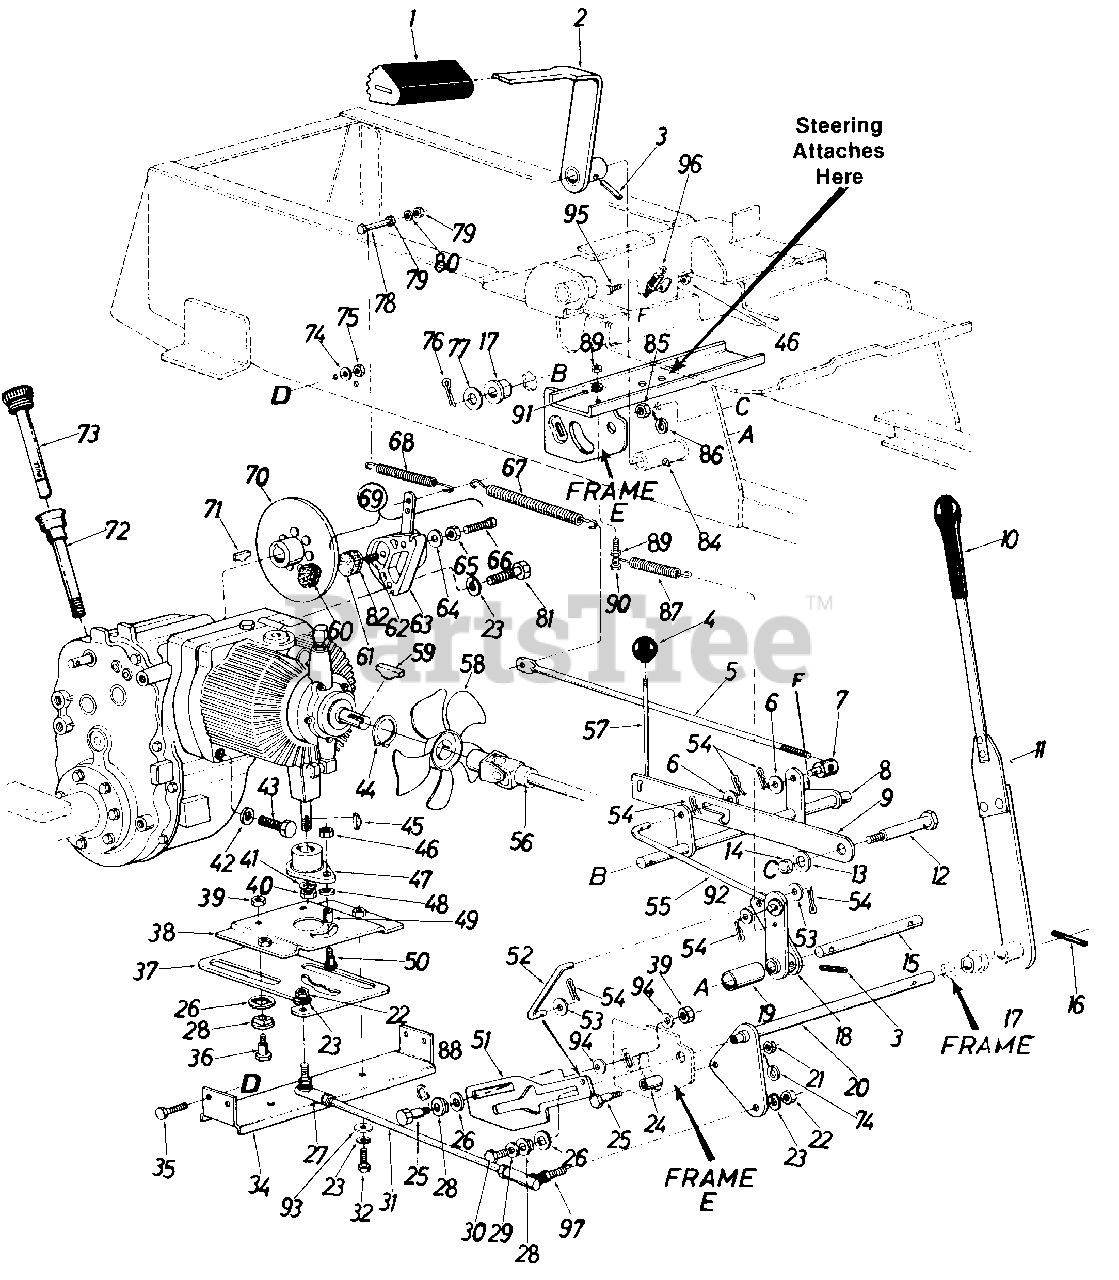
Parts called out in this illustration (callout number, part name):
1	Foot Pad
4	Ball Knob-Brake
5	Brake Rod
6	Fl-Wash. .375" I.D. x 1.00" O.D. x .030
7	Ferrule
8	Brake Transfer Shaft Ass'y.
9	Parking Brake Cam
10	G ri p
11	Control Arm Ass'y. Comp.
12	Shld. Scr. .62 Dia. x 2.75" Lg.
13	Fl-Wash. .460 I.D. x 1.24 O.D. x .06
14	Push Speed Nut for .625 Dia. Shaft
15	Brake Pivot Shaft
16	Spring Pin Spiral 1/4" Dia. x 1.50" Lg.*
17	Hex Flange Brg. Plastic .62 I.D.
18	Brake Hub Ass'y.
19	Spacer
20	Control Handle Ass'y.
21	Hex Cent. L-Nut 5/16-18 Thd.
22	Hex Nut 3/8-24 Thd.
23	L-Wash. 3/8" Scr.
24	Spacer
25	Shoulder Bolt
26	Fl-Wash. .63 Sq. Hole x 1.25" O.D.
27	Ball Joint Ass'y. 3/8-24 Thd.-L.H.
28	Pivot Slide
29	Fl-Wash. .312 I.D. x .88 O.D.
30	Hex Ins. Scr. 5/16-18 x 1.00" Lg.
31	Tie Rod
32	Hex Scr. 3/8-16 x .75" Lg.
34	Support Channel
35	Hex Scr. 5/16-18 x .75" Lg.
36	Shld. Scr. .437" Dia. x .350
37	Cam Plate
38	Slide Mtg. Plate Ass'y.
39	Hex Cent. L-Nut 5/16-18 Thd.
40	Hex Nut 1/2-13 Thd.
41	L-Wash. 1/2" Scr.*
42	Fl-Wash. .385 I.D. x .87 O.D. x .060
43	Socket Hd. Scr. 3/8-16 x 2.75" Lg.
44	Snap Ring
45	#5 Hi-Pro Key 1/8" x 5/8" Dia.
46	Hex Cent. L-Nut 1/4-20 Thd.
47	Pintle Plate Ass'y.
48	Fl-Wash. .281 I.D. x .50 O.D.
49	Needle Brg. .31" I.D. x .50" O.D. x .437" Lg.
50	Shld. Scr. .31 Dia. x .500
51	Neutral Control Slide
52	Neutral Control Rod
53	Fl-Wash. .312 I.D. x .630 O.D. x .063
54	Hairpin Cotter
55	Brake Link Rod Ass'y.
56	Universal Joint Ass'y. Comp.
57	Parking Brake Link
58	Fan Ass'y.
59	#61 H i-Pro Key 3/16 x 5/8 " Dia.
60	Lining-Brake
61	Lining-Brake
62	Actuator Pin
63	Housing with Lever and Pin
65	Nut
66	Adjustment Pin
67	Extension Spring .59 O.D. x 6.5" Lg.
68	Extension Spring
69	Disc Brake Ass'y. Comp.
70	Brake Disc Ass'y.
71	Hi-Pro Key 3/16 x 3/4" Dia.
72	Dipstick Tube Ass'y.
73	Dipstick Ass'y.
74	L-Wash. 5/16" Scr.
75	Hex Nut 5/16-18 Thd.
76	Cotter Pin 1/8" Dia. x 1.00" Lg. *
77	Fl-Wash. .635" I.D. x 1.00 O.D. x .120 Thk.
78	Hex Scr. 1/4-20 x 2.50" Lg.
79	Hex Nut 1/4-20 Thd.
80	L-Wash. 1/4" Scr.
81	Hex Scr. 3/8-16 x 1.25" Lg.
82	Backing Plate
84	Grease Fitting
85	Hex Nut 7/16-20 Thd.
86	L-Wash. 7/16" Scr.
87	Extension Spring
88	Wave Wash.
89	Hex Nut 1/4-20 Thd.
90	Hex Scr. 1/4-20 x 1.25" Lg.
91	L-Wash. 1/4 " Scr.
92	Fl-Wash.
93	Fl-Wash. .38 I.D. x 1.25 O.D.
94	Bell-Wash.
95	Hex Scr. 1/4-20 x 1/2" Lg.
96	Safety Switch
97	Ball Joint Ass'y. 3/8-24 Thd.-R.H.
